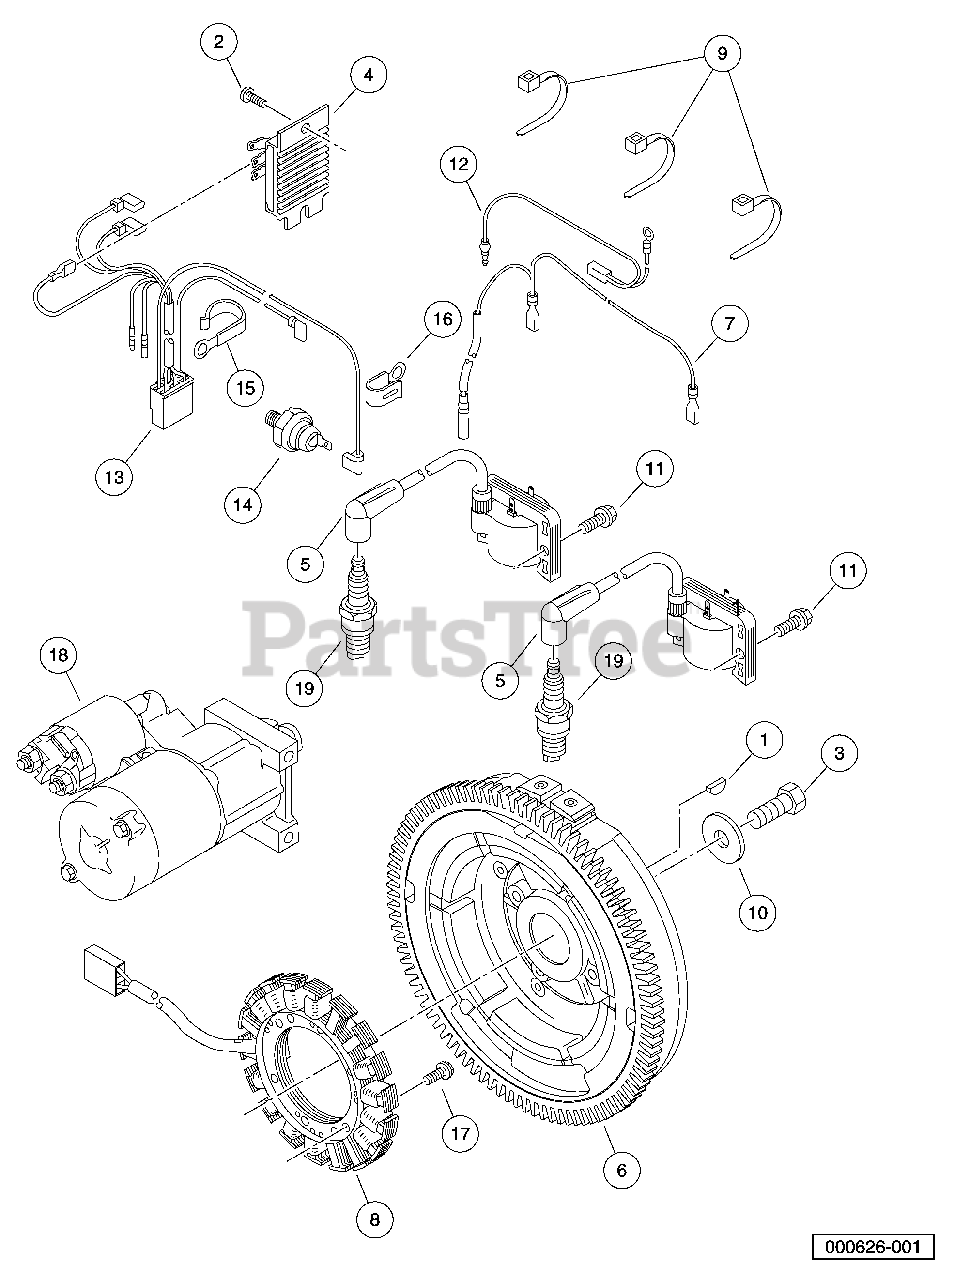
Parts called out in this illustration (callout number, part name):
3	Bolt, Flg, M12 X 1.25 X 30
4	Regulator, Voltage, Fh
5	Coil, Assy, Ignition, Fh
6	Flywheel, Assy, Fh
7	Harness, Regulator, Fh
8	Coil, Charging, Fh
9	Band, Harness, Fh
10	Washer, Flywheel, Fh
11	Bolt, Flanged, M6 X 20, Kaw
12	Harness, Ignition, Fh
13	Harness, Engine, Main, Fh
14	Switch, Oil Pressure, Fh
15	Clamp, Harness, Large, Fh
16	Clamp, Harness, Small, Fh
17	Screw, Pan, Coil Mount, Fh
18	Starter, Electric, Fh680d
19	Spark Plug, BPR2ES
